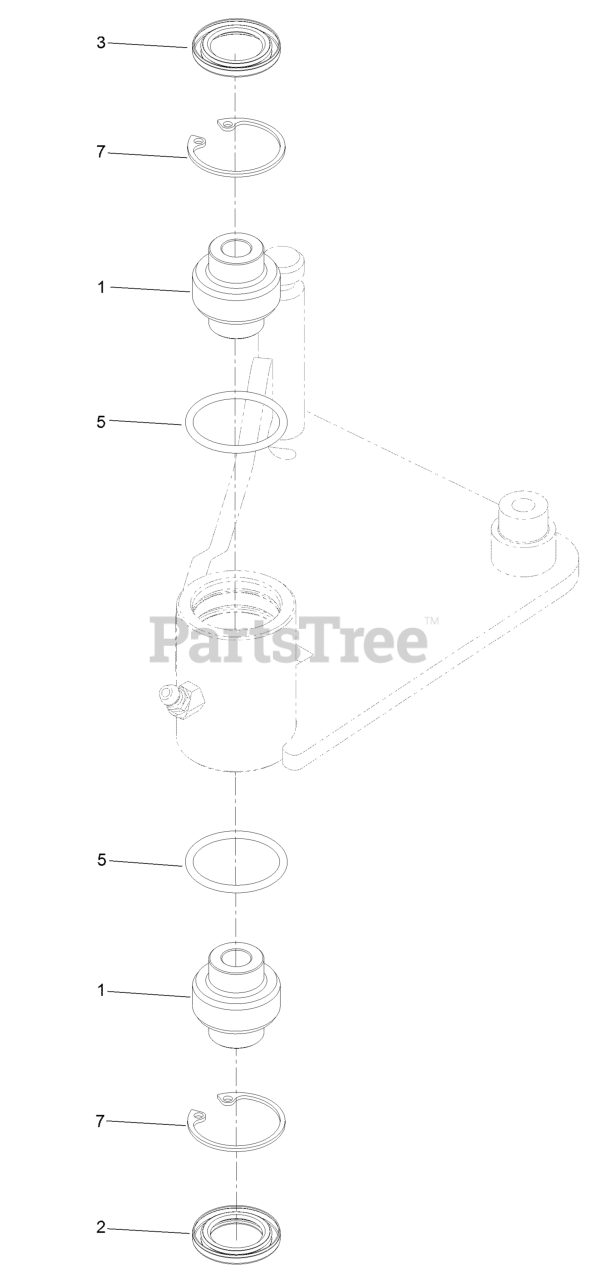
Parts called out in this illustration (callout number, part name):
1	Bearing-Spherical
2	Seal-Lip, Double
3	Seal-Lip, Single
7	Ring-Snap
